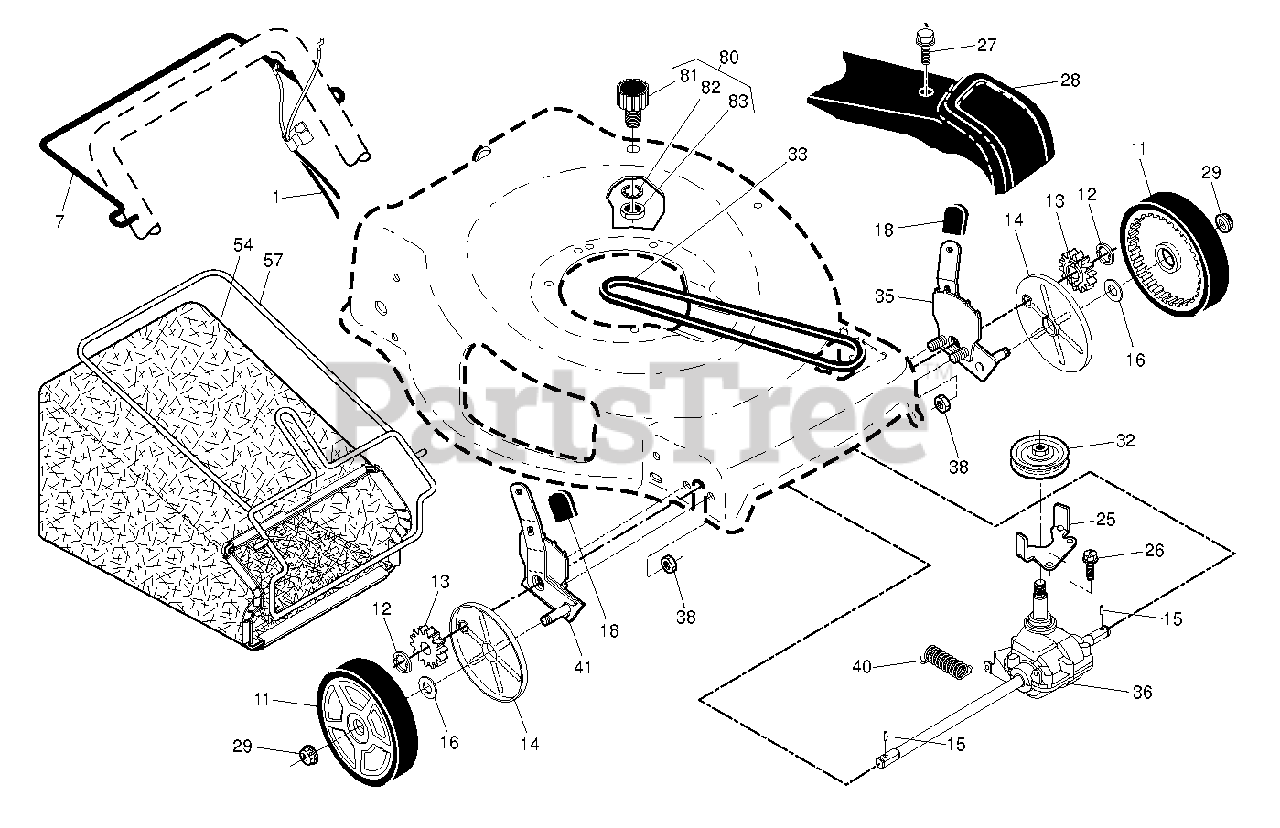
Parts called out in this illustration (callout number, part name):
1	CABLE.DRIVE.S/S.22+.FWGD
7	BAIL.DRIVE.S/S.ROUND.MARI.21
11	WHEEL.8X1.75.5SPK.RAD.YELLOW
12	E-RING 7/16 RE
13	PINION.14.TEETH.FGD
14	COVER.DUST.WHEEL.INNER.WALK
15	PAWL, DRIVE
16	WASHER FLUT
18	SELECTOR KNOB
25	BRACKET.BELT.GUIDE.22+FGD.BZP
27	SCREW, HEX HD TAPPING #10-24 1
28	COVER.DRIVE.PPRO FWGD ENG/FRE
29	NUT.HEX.FLANGE.3/8-16.LOCKNUT
32	PULLEY.DRIVEN.EZ/VARI (2 2MC)
33	BELT.DRIVE.FGD.
35	ADJUSTER.ASM.9.22+/RF/LR.21/LF
36	TRANSMISSION.22+.FWGD.SS
38	NUT.FLANGE.1-4-20-SERR
41	ADJUSTER.ASM.9.22+/RF/LR.21/LF
54	GBAG.A1640416S.BLK.PPRO.MRG.
57	Grass Bag Frame, 22+ Black
80	KIT.WASH-OUT.PORT
81	FITTING, HOSE, WATER WASHOUT
82	WASHER.LOCK.INTERNAL.TOOTH
83	LOCKNUT.HEX.WITH.O-RING
